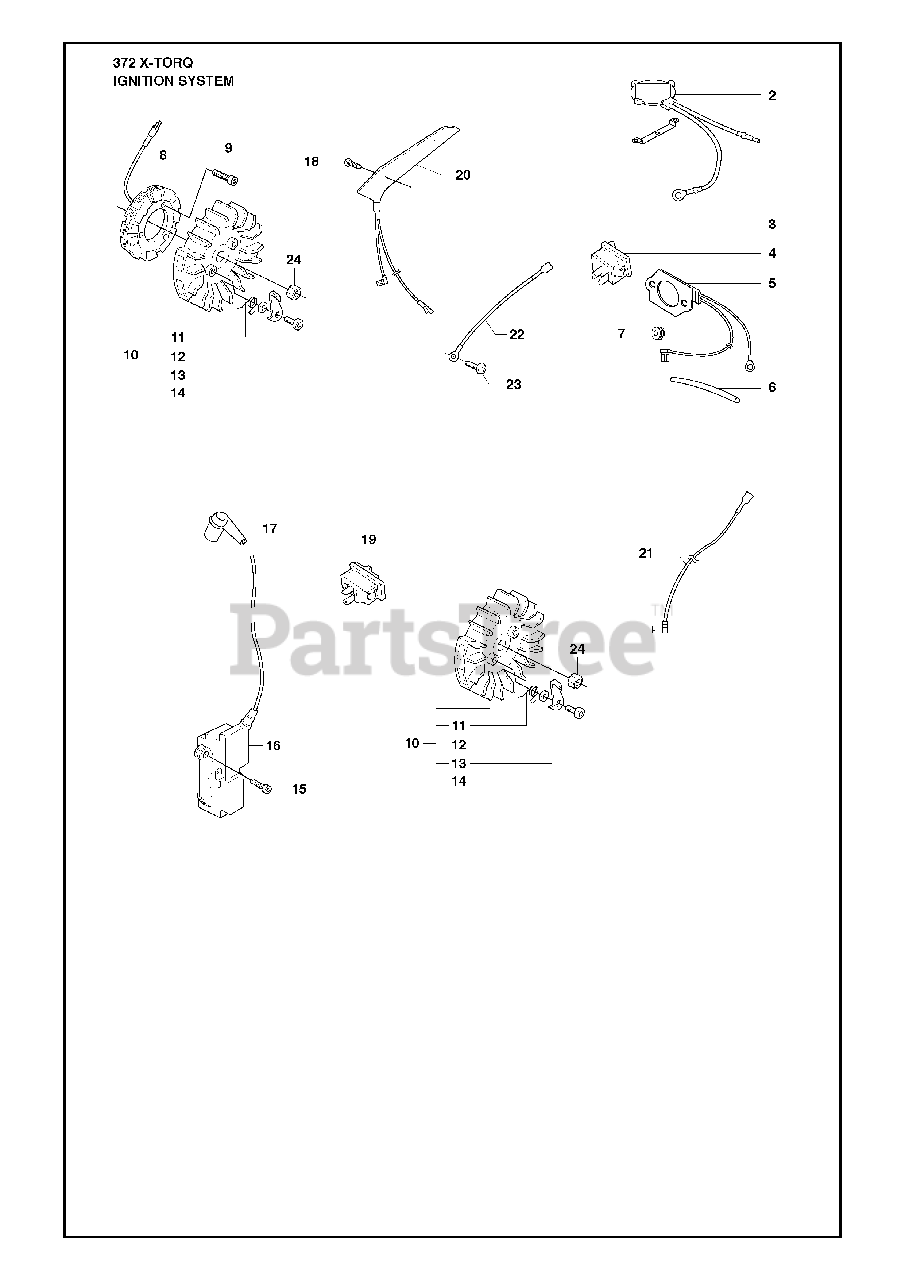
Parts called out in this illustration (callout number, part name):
2	THERMOSTAT
3	BRACKET
4	SWITCH
5	FOIL ELEMENT
6	TUBE
7	GROMMET
8	GENERATOR
9	SCREW
10	FLYWHEEL
14	SCREW M5X14
16	IGNITION MODULE
17	SPARK PLUG CONN. KIT
19	START/STOP SWITCH
20	PLATE (G)
24	NUT W/ WASHER
